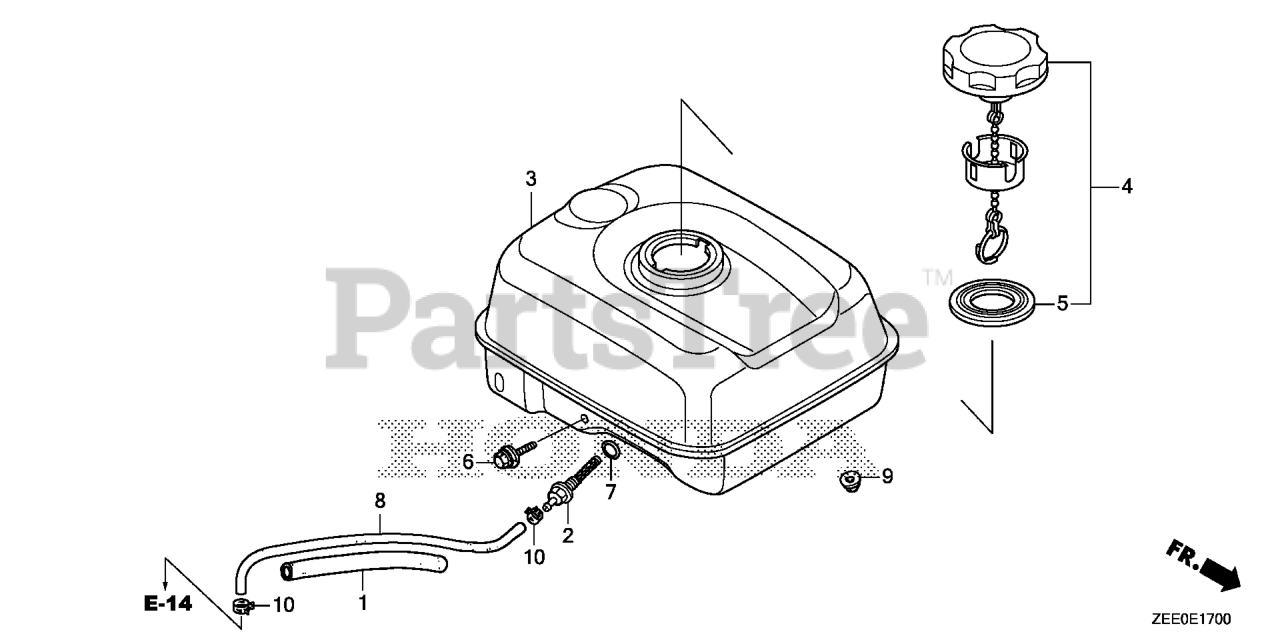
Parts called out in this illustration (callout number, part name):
1	RUBBER, SUPPORTER (107MM)
2	JOINT, FUEL TANK
3	TANK, FUEL *NH31* (MCKINLEY WHITE)
3	TANK, FUEL *NH1* (BLACK)
4	CAP, FUEL FILLER
5	GASKET, FUEL FILLER CAP
5	GASKET, FUEL FILLER CAP (39X62X3) (TOUYOUSYA)
6	BOLT, FLANGE (6X34)
7	O-RING (14MM) (ARAI) Use up to Engine SN 2949254.
8	TUBE, FUEL (4.5X145)
9	NUT, FLANGE (6MM)
10	CLIP, TUBE (D8)
